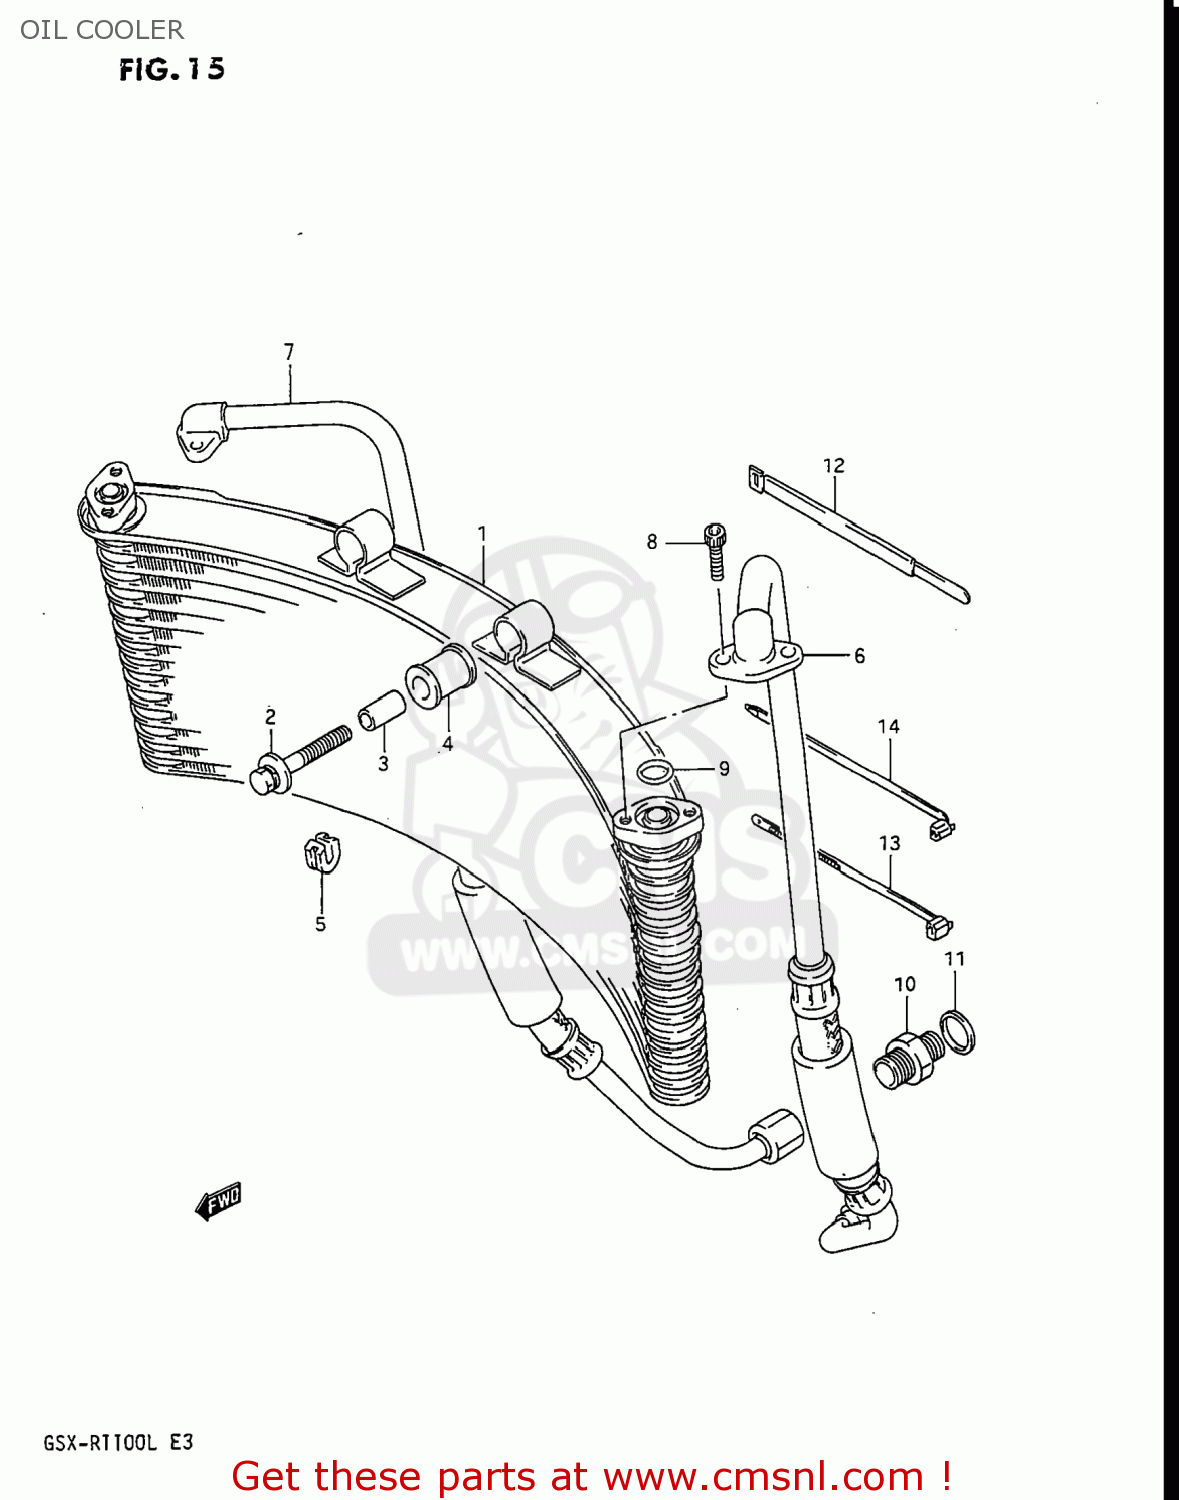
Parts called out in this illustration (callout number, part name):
1	COOLER ASSY,OIL
2	BOLT(8X40)
3	SPACER (8.8X12X24.5)
4	CUSHION,OIL COOLER NO.1
5	CUSHION,OIL COOLER NO.2
6	HOSE,OIL
7	HOSE,OIL
8	BOLT
9	O RING(D:2.4,ID:12.3)
10	BOLT UNION
11	GASKET(16X22X2) (NAS)
12	CLAMP(L:250)
13	CLAMP
14	CLAMP(L:235)
